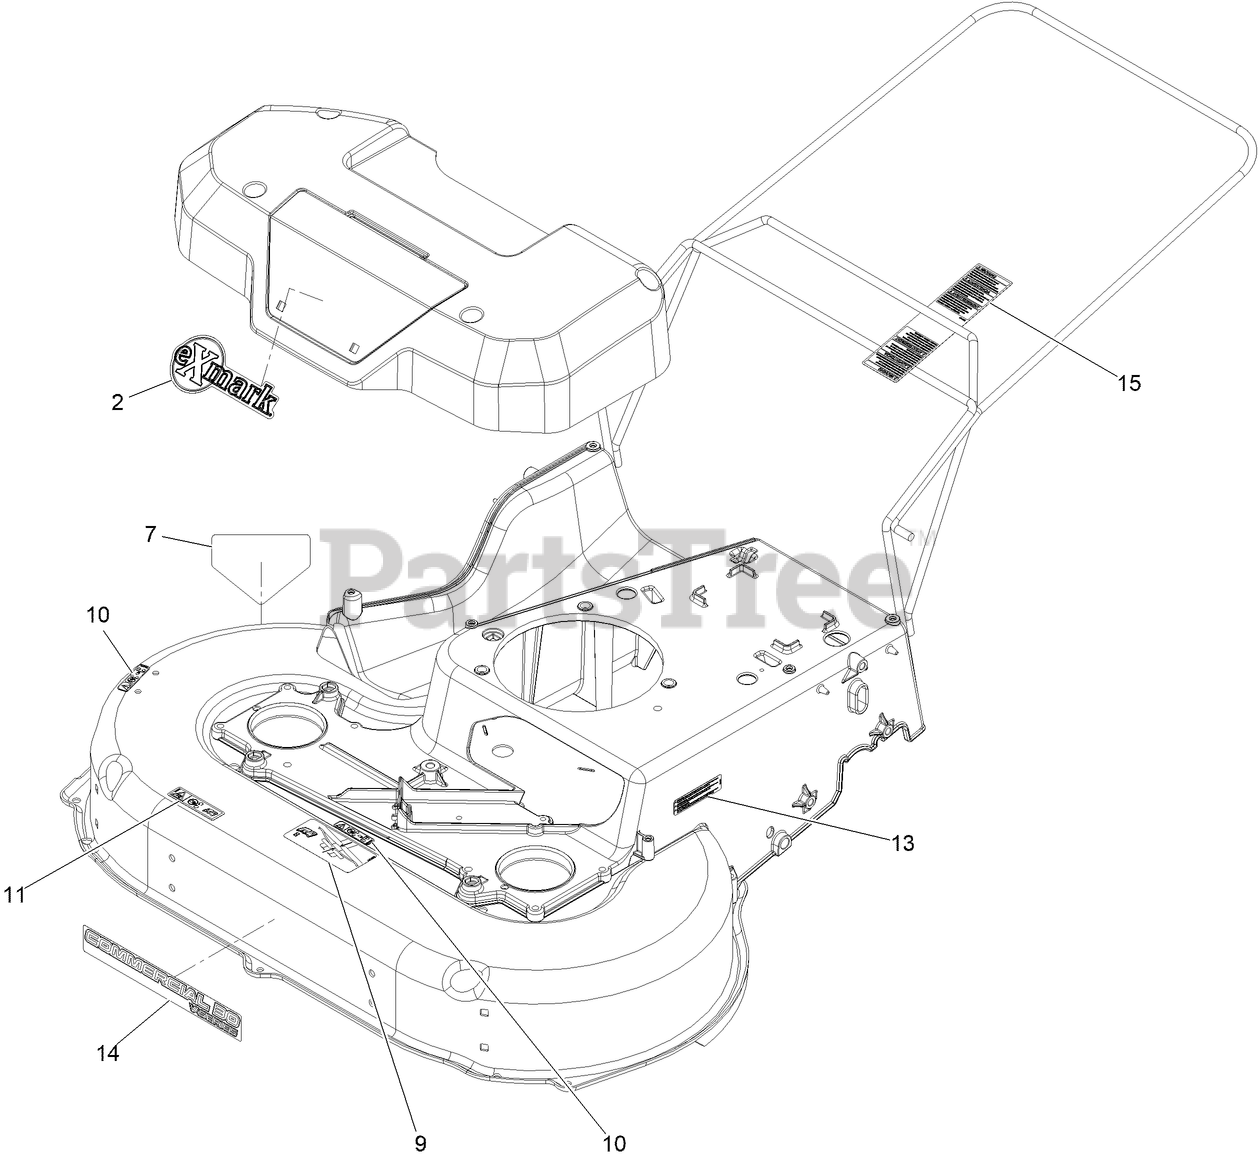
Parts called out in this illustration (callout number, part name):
2	DECAL-EXMARK LOGO
7	DECAL-DANGER
10	DECAL-WARNING
11	DECAL-WARNING
13	DECAL-PROP 65, SHORT, TRILINGUAL
14	DECAL-COMMERCIAL 30 V-SERIES
15	DECAL-WARNING (BAG)
